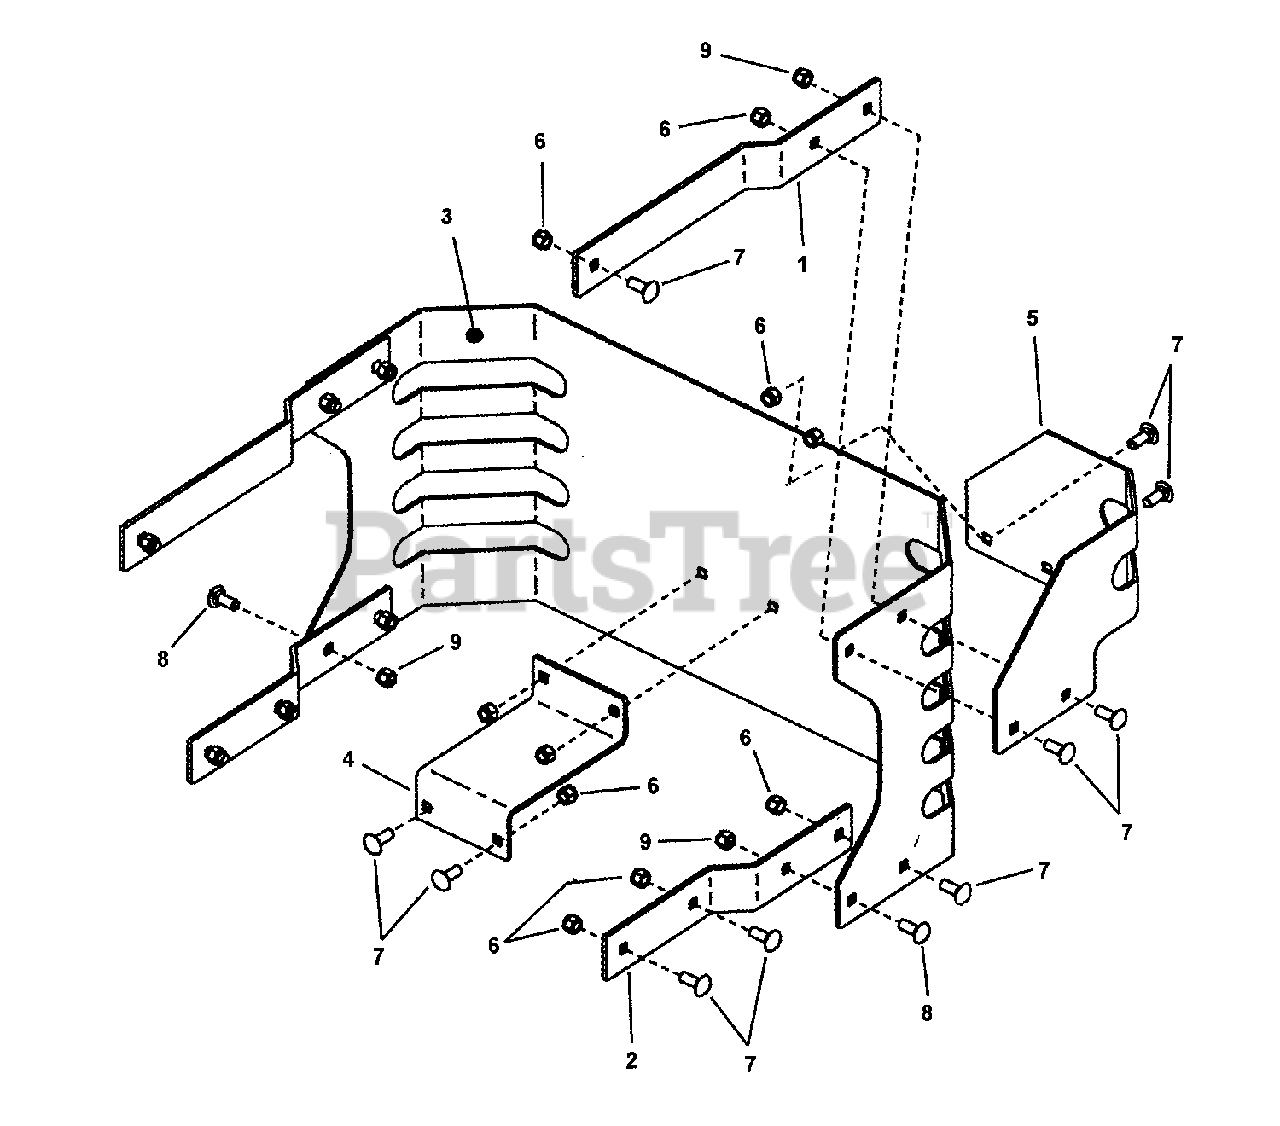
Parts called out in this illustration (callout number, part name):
1	UPPER BRACKET, Muffler Guard
2	MOUNT, Lower Muffler Guard
3	GUARD, Muffler (Back Plate)
4	REAR BRACE, Muffler Guard
5	GUARD, Muffler
6	NUT, 3/8-16 HEX NYLON LOCK
7	BOLT, 3/8-16 x 1" Square Neck Carriage GR5
8	BOLT, 3/8-16 x 3/4" Square Neck Carriage
9	NUT, 3/8-16 Hex Center Lock
